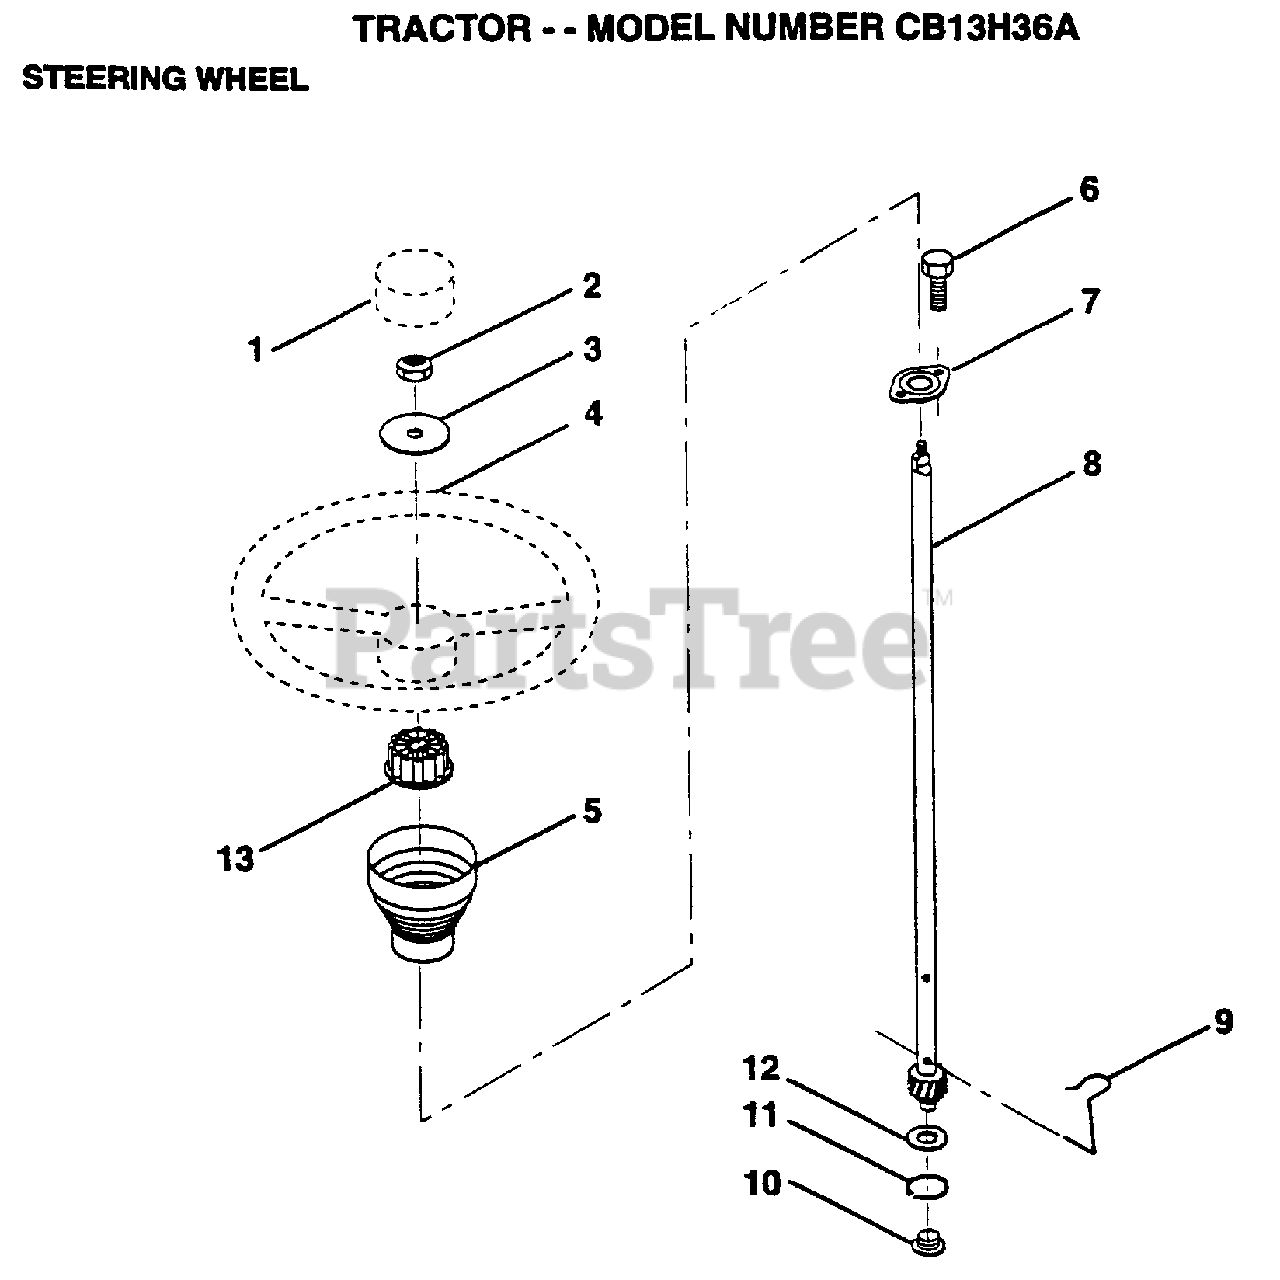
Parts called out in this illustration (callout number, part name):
1	ST WHL INSERT CAP
2	GRIPCO NUT
3	WASHER T
5	SLEEVE STEERING
9	STEERING CLIP
10	BUSHING STEER LWR
11	RING
12	WASHER LT
13	ADAPTER-WHEEL LT
